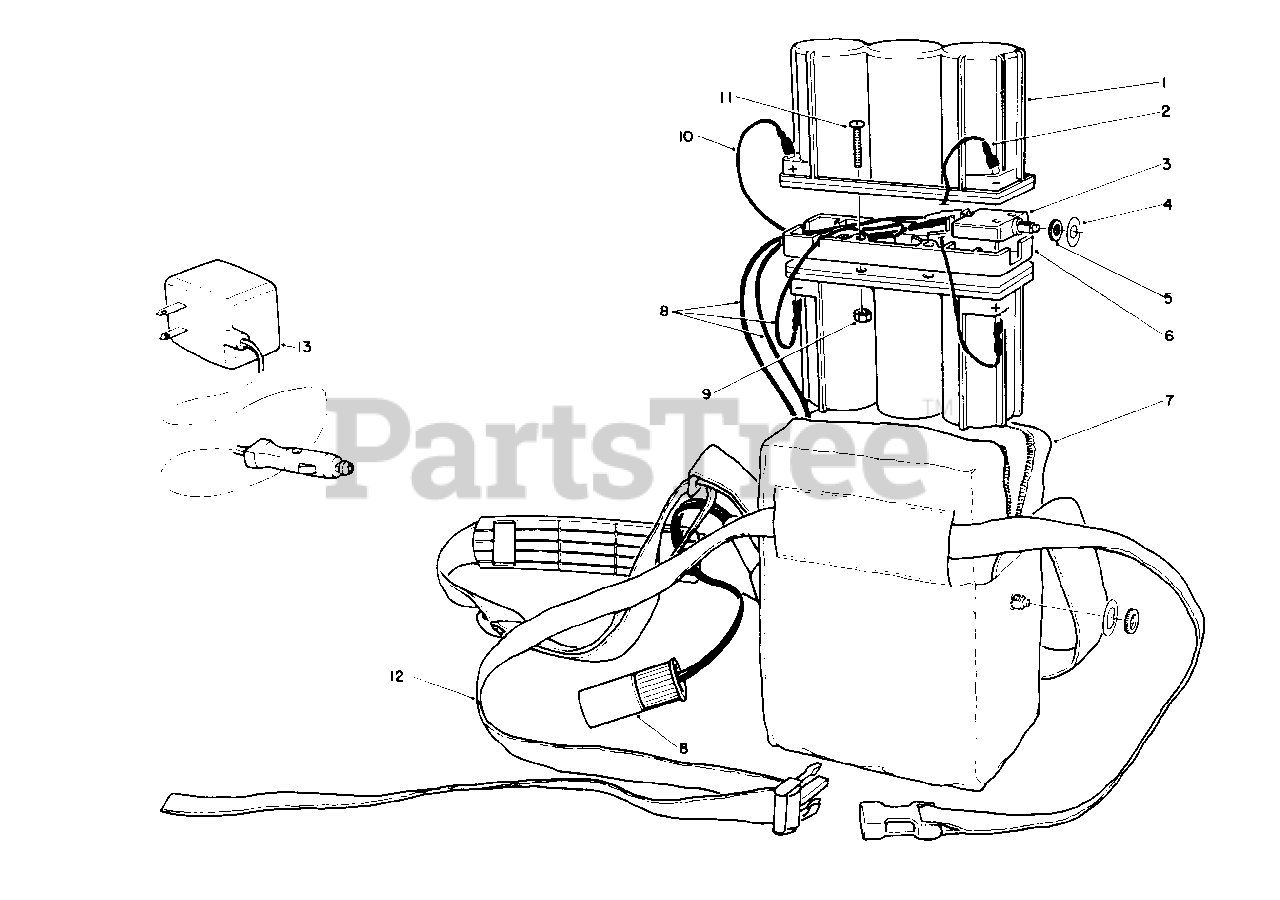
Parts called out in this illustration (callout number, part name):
1	Battery-6 Volt
2	Wire-Battery
3	Circuit Breaker
4	Plate-Breaker, Circuit
5	Nut-Knurled
6	Spacer-Battery
7	Pack-Soft
8	Cord-Battery
10	Wire-Breaker, Circuit
11	Screw-Phillips, Pan Hd.
13	Charger 12 Volt
